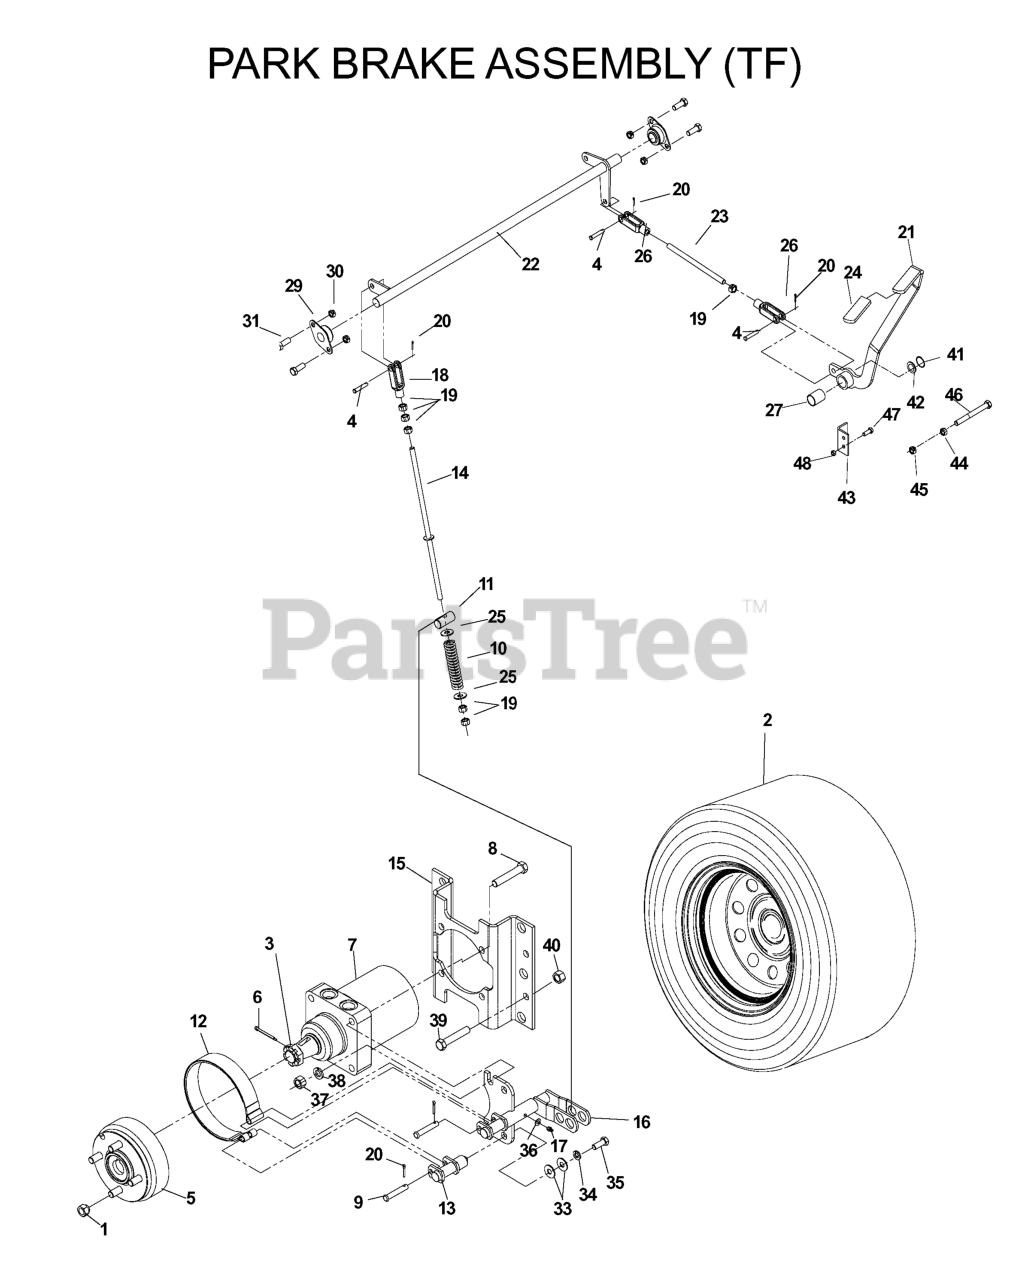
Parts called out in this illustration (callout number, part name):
1	LUG NUT 1/2F
2	WHEEL/TIRE.ASM.23X10.5-12.GREY
3	NUT 3/4-16 HEX SLTD GR5 ZD
4	CLEVIS PIN 3/8 X 1 1/8
5	HUB W/BRAKE DRUM
6	PIN COTTER 4MM X 45MM
7	MB WHEEL MOTOR
8	HCS 1/2C X 2 3/4
9	CLEVIS PIN
10	COMPRESSION SPRING
11	TRUNION PIN
12	BRAKE BAND
13	BRAKE BAND SUPPORT
15	MOTOR STANDOFF
16	BRAKE WLDMNT
17	ZERK
18	YOKE-3/8-24 PLTD
20	RP_COTTER PIN 1/8 X 3/4
21	BRAKE LEVER WLDMT
22	BRAKE CROSS SHAFT
23	LINKAGE - SHORT
24	GRIP, PARK BRAKE
25	WASHER, 7/16 DISC SPRING
26	YOKE-3/8-24 PLTD
29	FLANGE BEARING
30	NUT 3/8-16 NYLOC
31	HCS 3/8-16X1.GRD.5.ZD
32	RP_COTTER PIN 1/8 X 3/4
33	WASHER 3/8 FLAT
34	SLW 3/8 STD
35	HEX BOLT 3/8 X 1"
37	NUT HEX 1/2
38	WASHER 1/2" SPLIT LOCK
39	HCS 1/2C X 1 1/4 SERRATED HEAD
40	NUT 1/2-13 HEX NYLOC ZD
41	RETAINING RING, 7/8"
42	BSHG .875 X 1.375 X .074 ZD
44	NUT 3/8C WHIZ
45	NUT 3/8-16 NYLOC
46	HCS 3/8C X 2 1/2
47	HCS 1/4C X 3/4 HCS
48	NUT.1/4-20.HEX.NYLOC.ZD
539105983	RIM 0 OFFSET 8.5" WIDE
539107392	RIM.12X7.GRAY.+1".OFFSET.ZTR
539107431	TIRE.TURF.MASTER.23X10.5-12
539107432	TIRE - 23X8.5-12
539912234	VALVE STEM TR-412
